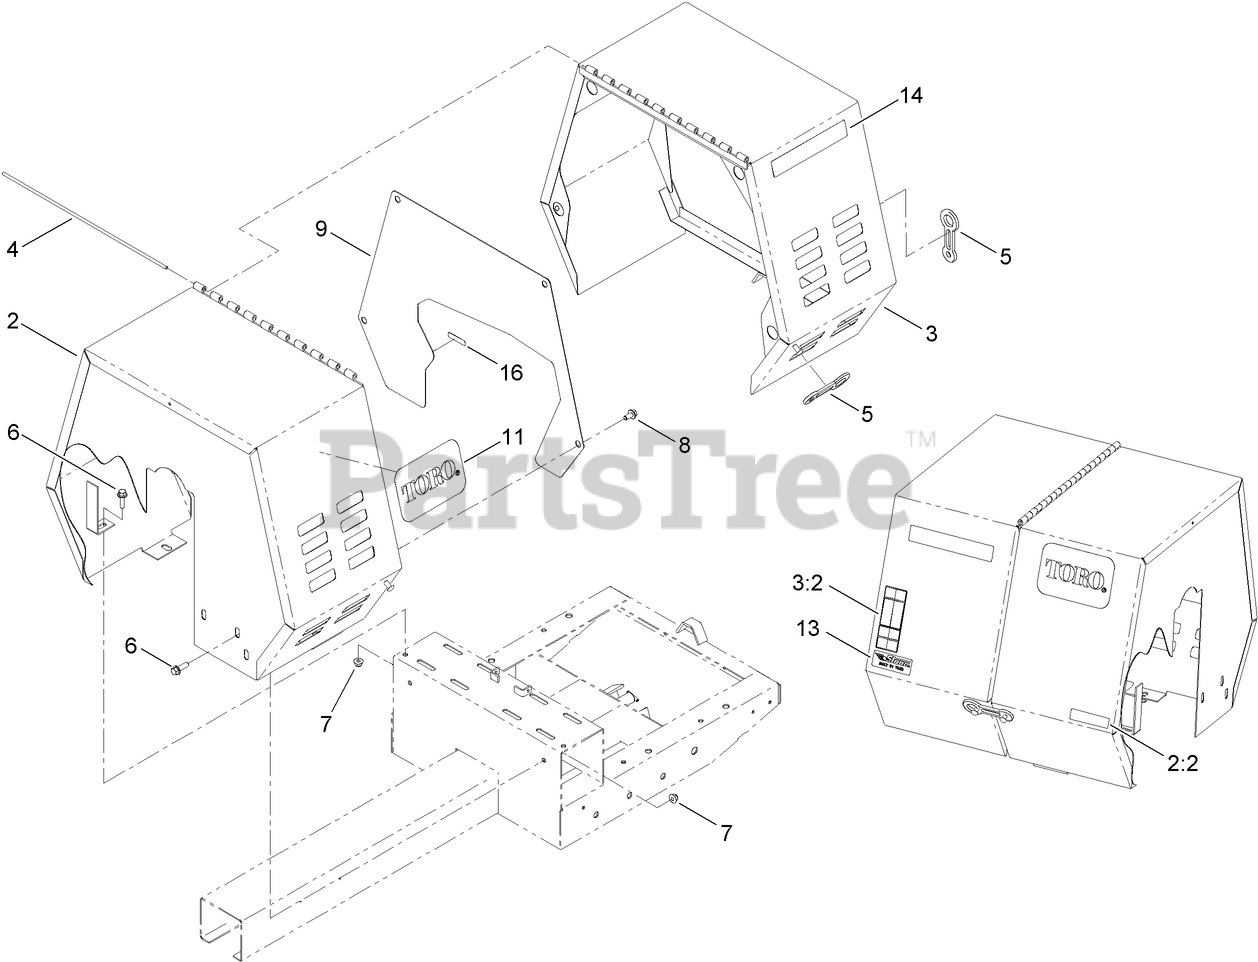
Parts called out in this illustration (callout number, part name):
2	STATIONARY COWL ASM
2:2	DECAL-ARRESTER, SPARK
3	MOVABLE COWL ASM
3:2	DECAL-WARNING
5	LATCH-RUBBER
6	SCREW-HHF
7	NUT-HF, NI
8	SCREW-HWH
9	PLATE-ACCESS, BELT
11	DECAL
14	DECAL-MM-658H
16	DECAL-GREASE
